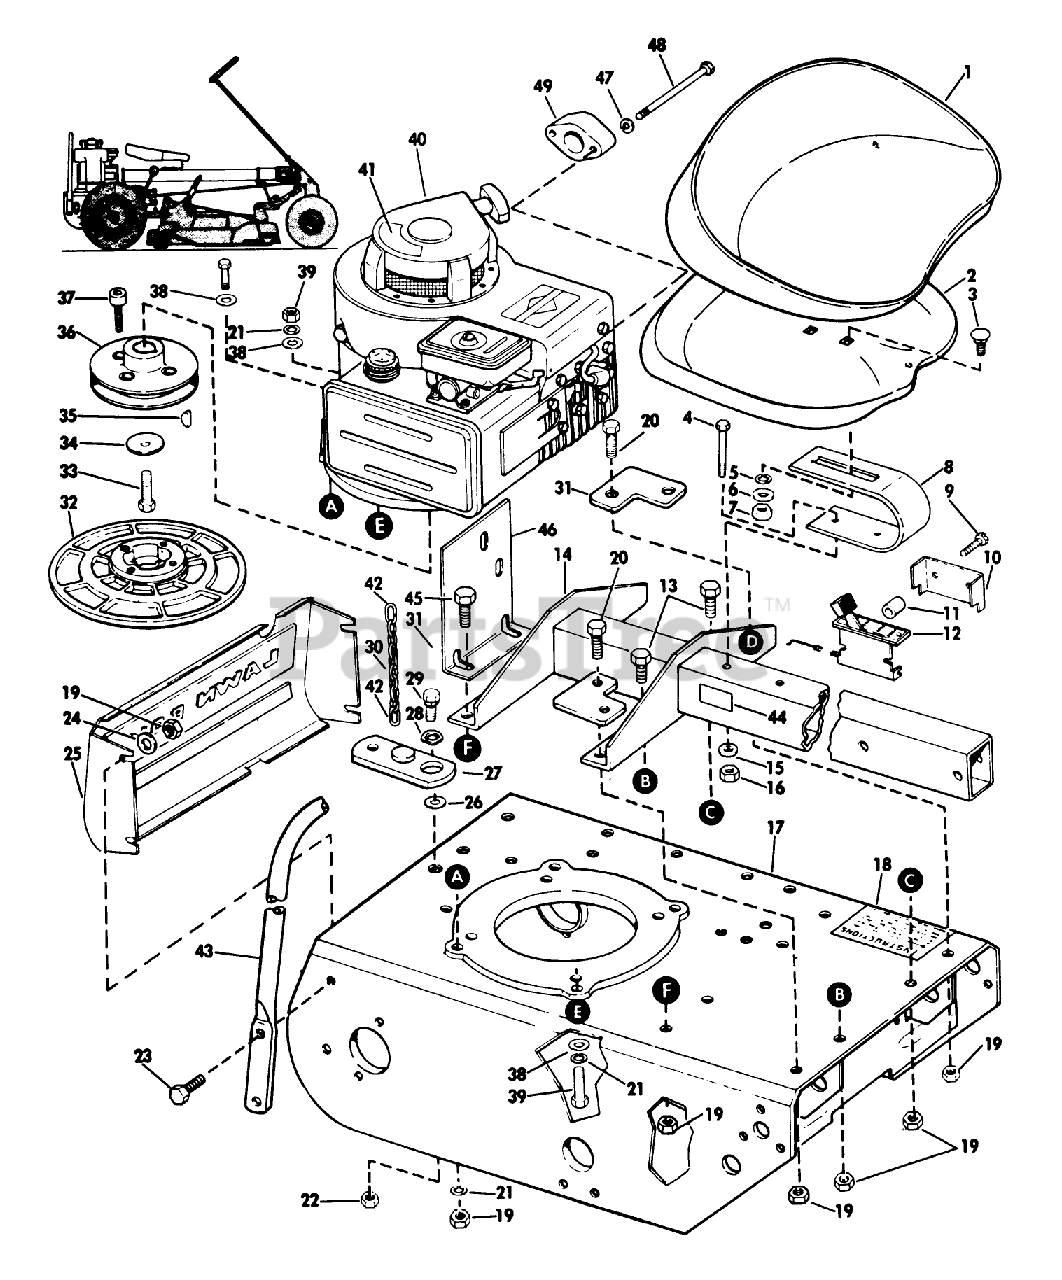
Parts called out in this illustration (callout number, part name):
40	Engine-5 H.P. Briggs and Stratton Model 146702, 0652-01
42	Lap Link
44	Plate-Model No.
